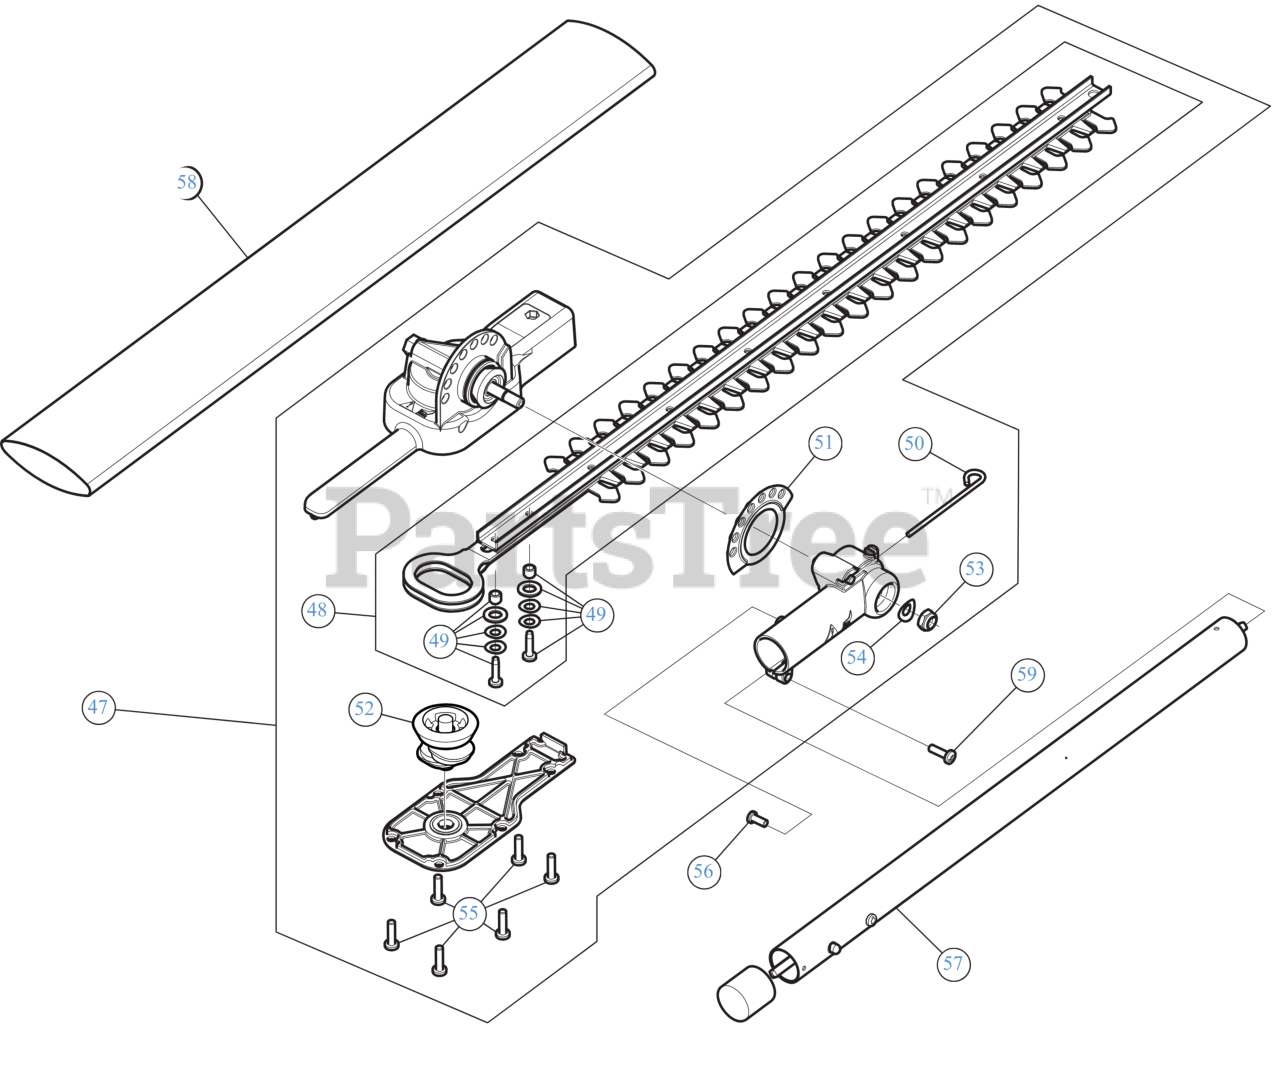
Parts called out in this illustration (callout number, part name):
47	GEARBOX ASSEMBLY
48	BLADE ASSEMBLY
49	BLADE HARDWARE
50	LOCKING LEVER PIN
51	SPACER DETENT SHM
53	NUT 5/16-24
54	SHAKE PROOF WASHER
55	SCREW - 10-24X.625 PAN HEAD
56	SCREW 8-32X.437
57	BOOM ASSEMBLY
58	BLADE COVER
59	SCR, M5 x 15.8MM
